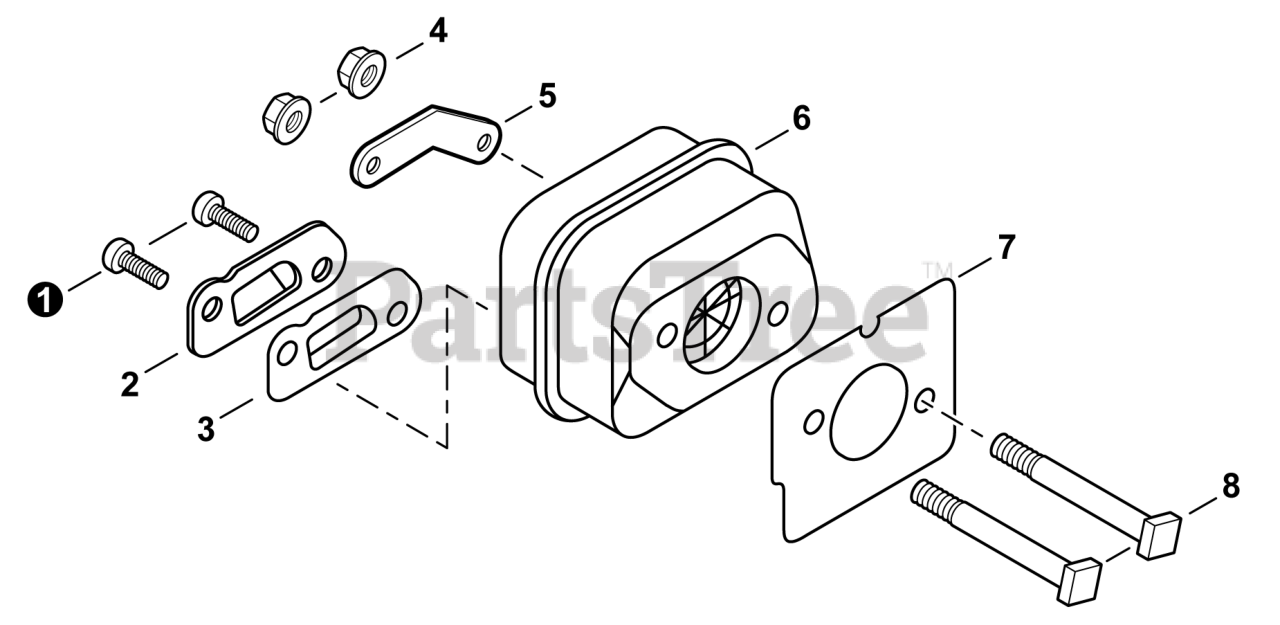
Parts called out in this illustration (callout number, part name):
1	SCREW 4x8
2	GUIDE, EXHAUST
3	SCREEN, SPARK ARRESTER
4	NUT, FLANGE M5
5	PLATE, EYE
6	MUFFLER
7	GASKET, EXHAUST
8	BOLT 5x62
